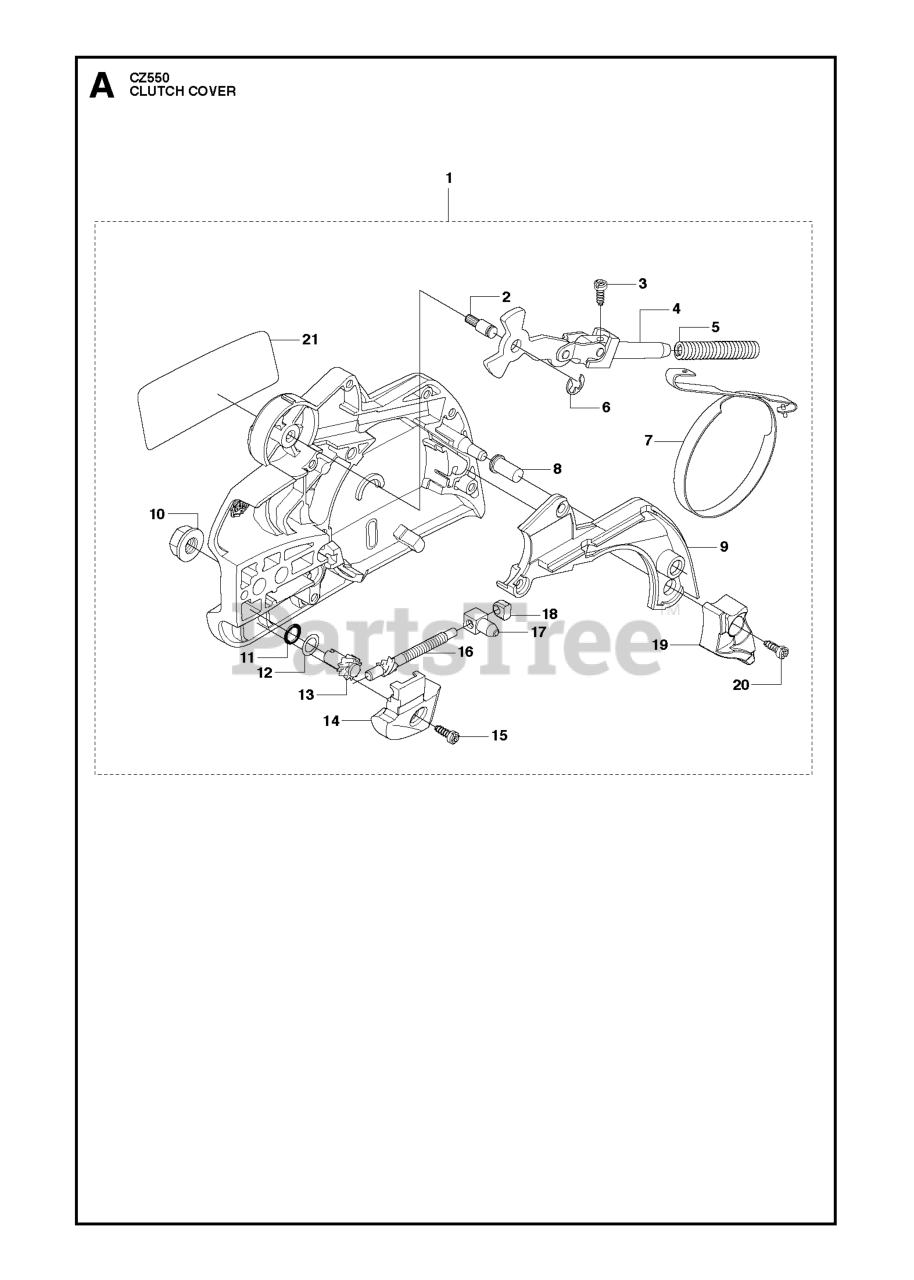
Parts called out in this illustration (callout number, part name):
1	CLUTCH COVER ASSY STD REDMAX
2	PIN KNEE JOINT
3	SCREW CCRPANT
4	KNEE JOINT ASSY
5	BRAKE SPRING
6	E-RING 4
7	BRAKE BAND ASSY
8	GUIDE BUSHING
9	COVER, CHAIN BRAKE
10	NUT M8 FLANGE
12	WASHER STEEL
13	WORM WHEEL
14	CHAIN GUIDE
15	SCREW CCRPANT
18	BEARING SLEEVE
19	WEAR GUARD, CHAIN
20	SCREW CCRPANT
21	LABEL CLUTCH COVER REDMAX
